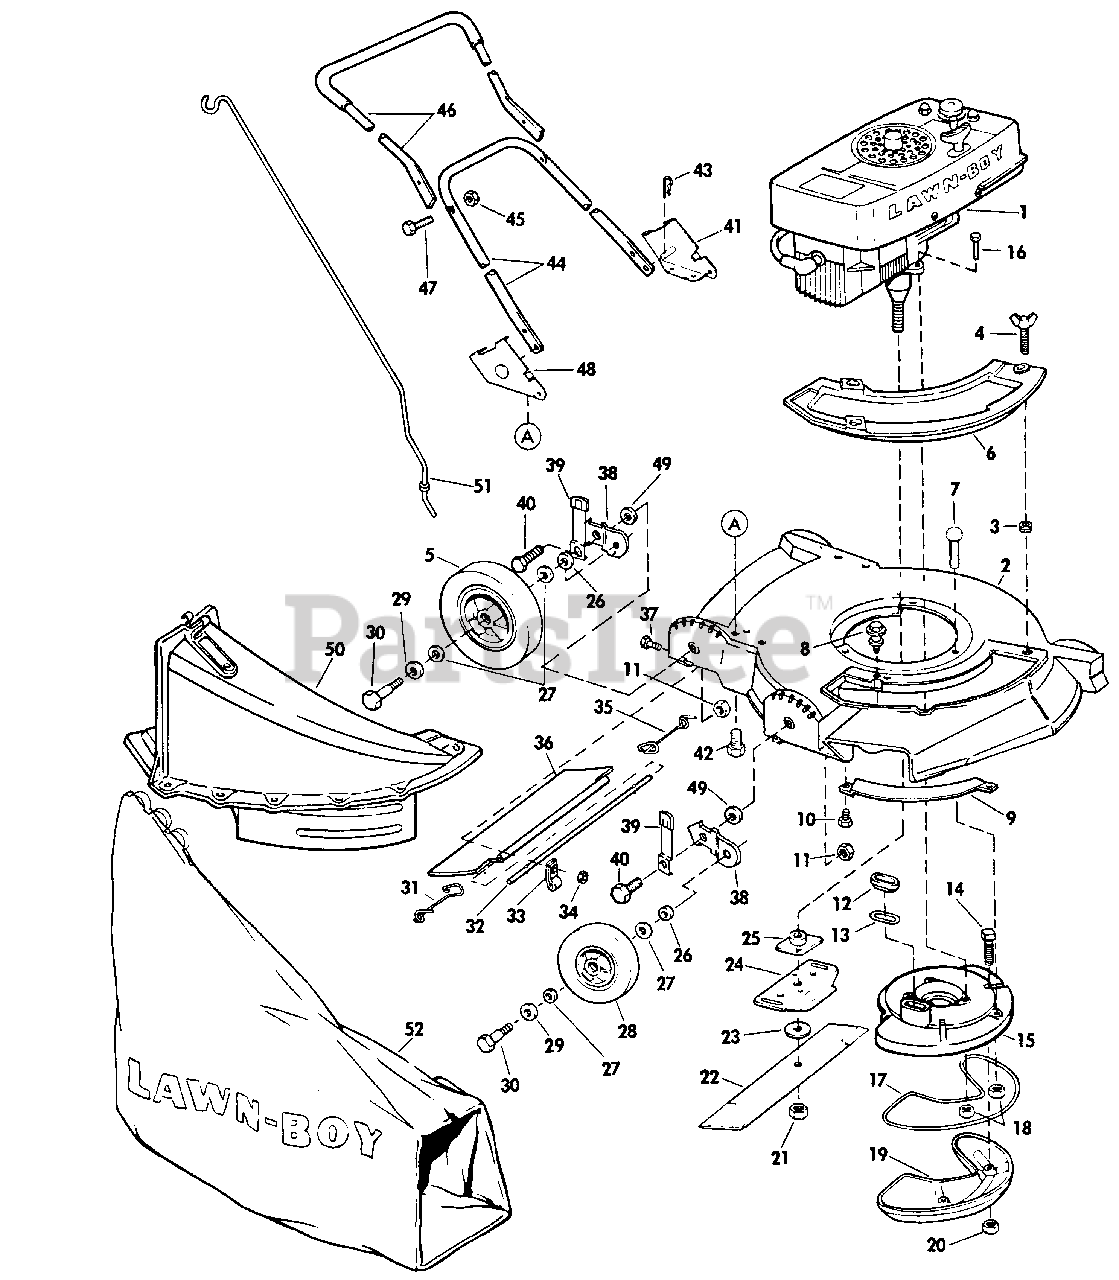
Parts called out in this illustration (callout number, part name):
1	See Note #2 at bottom of this page.
2	Housing & Cover Plate-21"
3	Grommet (Also Included in 681536 19" Housing)
4	Screw
5	Wheel & Tire-8"
6	Cover-Chute (19" & 21" Models)
7	Screw-Muffler Plate to Housing
8	Bolt
9	Toe Bar-19" Models
9	Toe Bar-21" Models
10	Screw
11	Nut
12	Sleeve-Muffler Gasket
13	Gasket-Exhaust
14	Screw-Muffler to Muffler Plate
15	Muffler Plate Assy
16	Screw
17	Gasket-Muffler
18	Nut
19	Muffler
20	Nut-Muffler
21	Nut-Blade
22	Blade-21"
22	Blade-19"
23	Washer (21" Models Only)
24	Stiffener-Blade
25	Collar & Plate Assembly
26	Washer
27	Felt Washer
28	Wheel & Tire-6"
29	Washer-Wheel Bolt Head
30	Bolt-Shoulder, Wheel-Front & Rear
31	Spring-R.H.
32	Rod-19" Models
33	Clamp
34	Nut
35	Spring-L.H.
36	Shield-19" Models
36	Shield-21" Models
37	Screw
38	Wheel Hgt. Adj. Bracket
39	Knob & Spray Ay.
40	Bolt-Shoulder
41	Bracket-Handle-Left
42	Screw
43	Hairpin
44	Handle-Bottom
45	Nut-Handle
46	Handle-Top
47	Screw-Handle
48	Bracket-Handle-Right
49	Washer
50	Chute
51	Rod
52	Grass Bag
